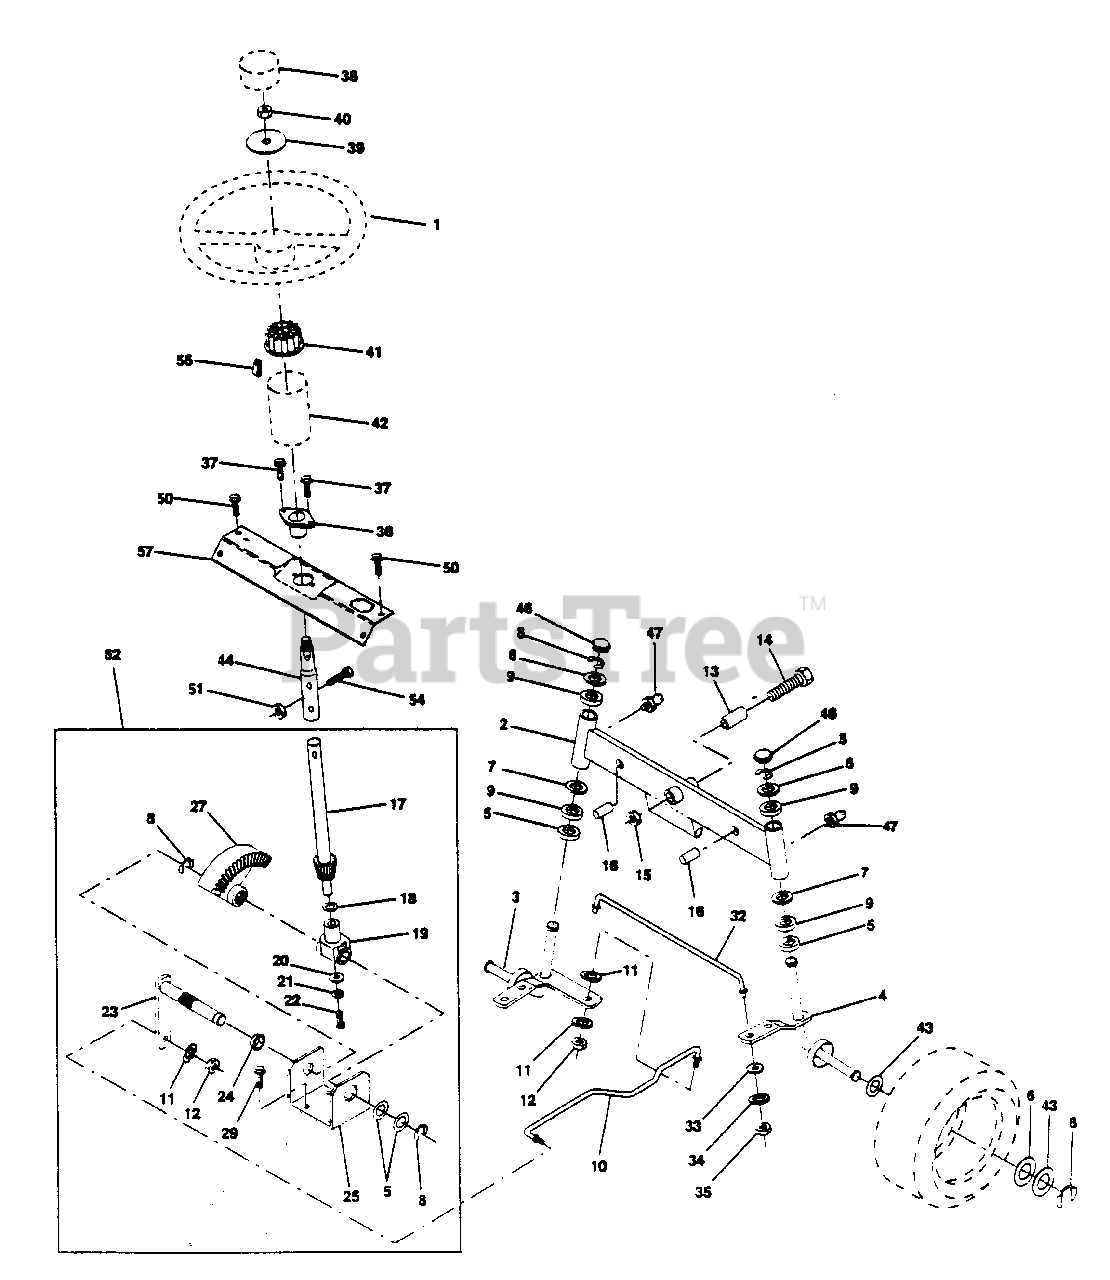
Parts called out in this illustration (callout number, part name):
1	Wheel Steering Auto Black (AYP part number)
2	Axle Asm Fr LT W/gzks 38/42 (AYP part number)
3	Spindle Asm LH (AYP part number)
4	Spindle Asm RH
5	Bearing Race Thrust Harden (AYP part number)
6	Washer 25/32 X 1-5/8 X 16ga (AYP part number)
7	Washer 27/32 X 1-1/4 X 16 Ga (AYP part number)
8	Ring Klip #t5304-75 (AYP part number)
9	Bearing Col Strg Blk (AYP part number)
10	Link Drag Sol Ball Jt 20 064 (AYP part number)
11	Washer Lock Hvy Hlcl Spr 3/8 (AYP part number)
12	Nut Fin Hex 3/8-24 Unf (AYP part number)
13	Spacer Bearing Axle Front (AYP part number)
14	Bolt Hex 5/8-11 Unc X 3-1/2 (AYP part number)
15	Nut Lock Flange 5/8-11 Unc (AYP part number)
16	Pin Axle 5/8 X 1 55/1 54 Lg (AYP part number)
17	Shaft Asm Strg Private Label (AYP part number)
18	Washer Thrust 515x 750x 033 (AYP part number)
19	Support Shaft (AYP part number)
20	Washer Shim 1/4 X 5/8 X 062 (AYP part number)
21	Washer Lock Hvy Helical 1/4 (AYP part number)
22	Screw Hex Socket 1/4-20 X 5/8 (AYP part number)
23	Shaft Asm Pittman (AYP part number)
24	Nyliner Snap In (AYP part number)
25	Bracket Steering (AYP part number)
27	Gear Sector 22 Teeth (AYP part number)
29	Screw Thdrol 3/8-16x3/4 Ty-tt (AYP part number)
32	Rod Tie Wire Form 19 75 Mech (AYP part number)
33	Bushing Link Drag Blk LR (AYP part number)
34	Washer 13/32 X 7/8 X 16ga (AYP part number)
35	Pin Cotter 1/8 X 3/4 Cad (AYP part number)
36	Bushing Strg (AYP part number)
37	Screw Slftp #10-16 X 1/2 Ty-b (AYP part number)
38	Insert Cap Strg Wh Au Gen Blk (AYP part number)
39	Washer 13/32 X 2-3/8 X 8 Ga (AYP part number)
40	Nut Lock Center 3/8-24unf (AYP part number)
41	Adaptor Wheel Strg 640/ 635id (AYP part number)
42	Boot Shaft Steering (AYP part number)
43	Washer 25/32 X 1 1/4 X 16 Ga (AYP part number)
44	Shaft Extension Steering (AYP part number)
46	Cap Spindle Fr Top Blk (AYP part number)
47	Fitting Grease (AYP part number)
50	Screw Hex Wsh Thdrol 1/4-20 x 3/4 (AYP part number)
51	Nut Lock Hex w/Insert 5/16-18 (AYP part number)
54	Bolt Fin Hex 5/16-18 unc x 1-1/4 (AYP part number)
55	Clip Tinnerman (AYP part number)
57	Support Shaft Steering (AYP part number)
62	Steering Assembly (AYP part number)
